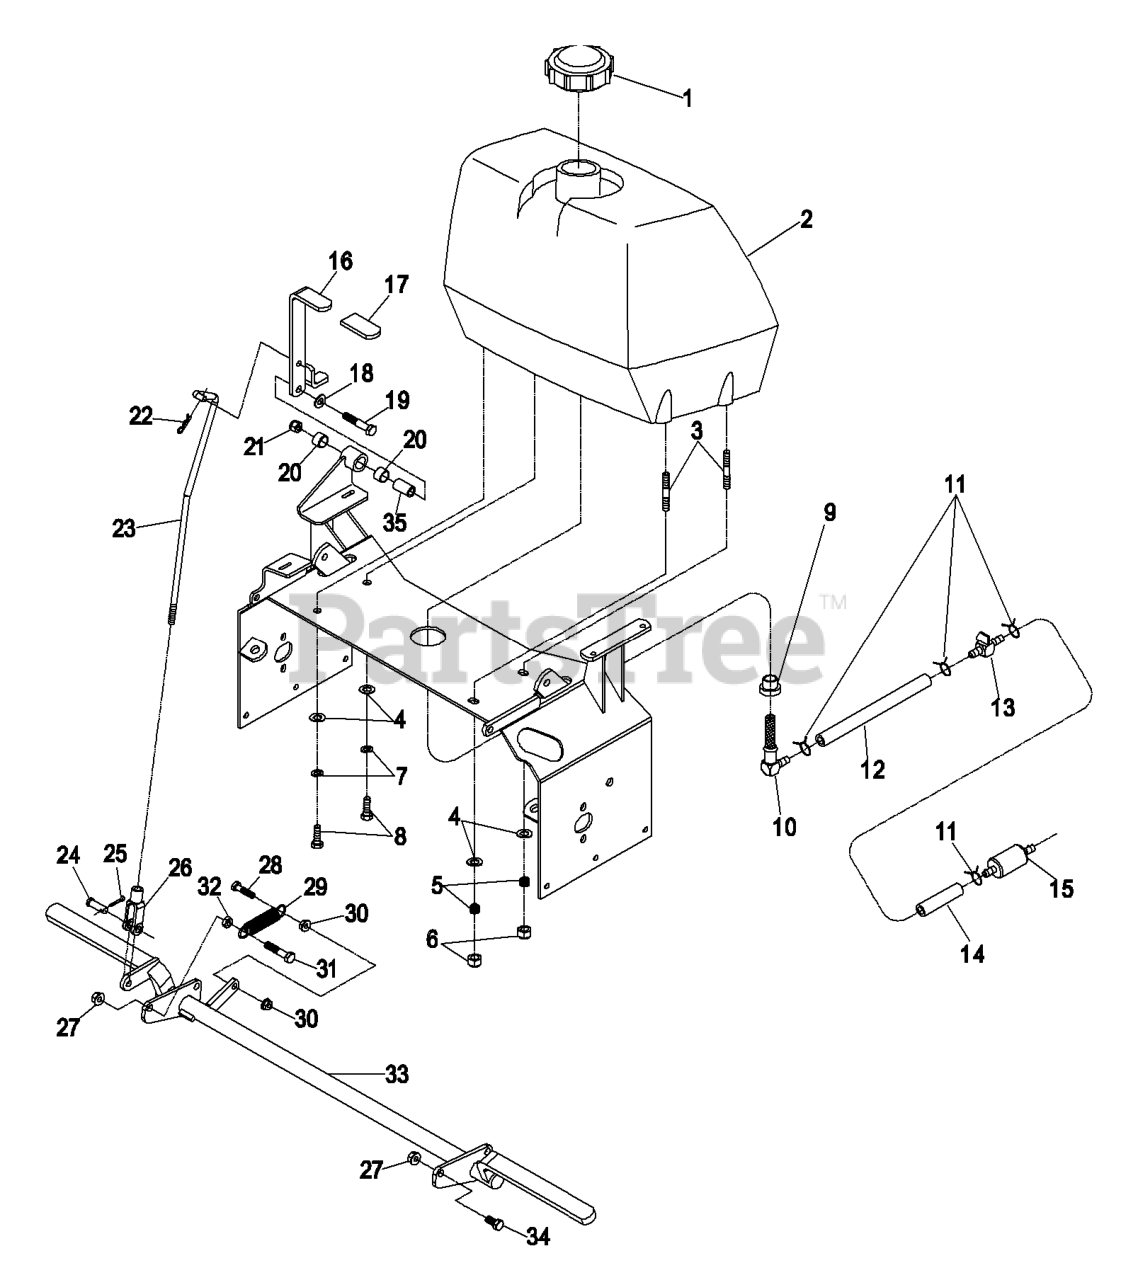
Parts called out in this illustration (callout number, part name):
1	CAP-FUEL
4	WASHER-PLAIN
5	SPRING-TANK, FUEL
6	NUT-LOCK, NI
7	WASHER-LOCK
8	SCREW-HH
10	ELBOW-TANK, FUEL
13	VALVE-FUEL
14	HOSE-LINE, FUEL
15	Kohler Part No. 2405002 Fuel Filter
17	GRIP-LEVER
18	WASHER-FLAT
19	SCREW-HH
20	SLEEVE-BUSHING
21	NUT-LOCK, NI
22	PIN-COTTER
23	LINKAGE,PARK BRAKE
24	PIN-CLEVIS
25	PIN-COTTER
26	YOKE-LINKAGE, BRAKE
27	NUT-HHF, WHIZ
28	SCREW-HH
29	SPRING-IDLER
31	SCREW-HH
32	NUT-JAM
34	SCREW-HH
35	BUSHING-PIVOT
